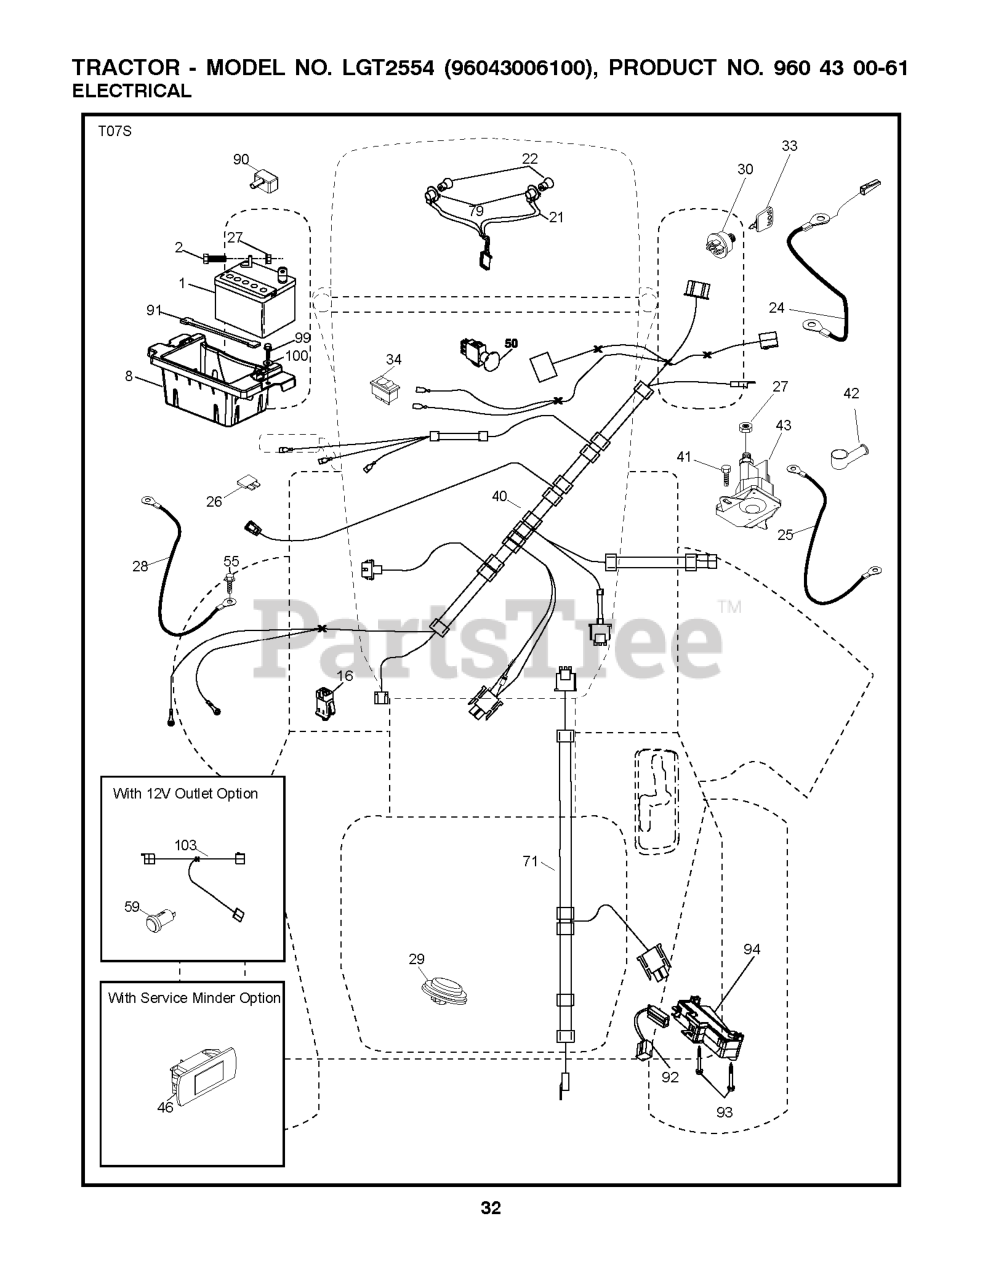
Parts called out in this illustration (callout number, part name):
1	Battery 12 Volt 25 Amp
2	BOLT.HEX.1/4.X.3/4.DICHROMATE
8	BOX.BATTERY.MOUNT.FRONT.LT
16	SWITCH INTERLOOK PUSH-IN
21	HARNESS ASSY LIGHT
24	CABLE.BATT.POS.WIRE.TG.DA SOL
25	CABLE.STARTER.6G.BL/RED.17.5
26	FUSE 20AMP
27	NUT
28	CABLE GROUND 6 GA 21" 90T BLK
29	SWITCH.SEAT.DELTA.OPC.
30	SWITCH.IGN.DELTA.W.LGH.ROS
33	KEY.CHAIN.BLISTER.PACK.GEN.INT
40	HARNESS.IGN.DASH.HUQ/P
41	SCREW
42	TERMINAL COVER
43	SOLENOID.W/BRASS.PLUNGER
46	RP.GUAGE.SRVCMNDR.HRMTR.
50	RP.PTO.SWITCH.8 TERMINAL.BLACK
55	SCREW 5/16"
59	OUTLET.12-VOLT
71	HARNESS-CHASSIS SUB
79	BULB HOLDER ASM.
90	COVER.TERMINAL.BATTERY
91	STRAP.BATTERY.MOUNT.FRONT(2 2)
92	HARNESS.PIGTAIL.CONSLE
93	SCREW.PLASTITE
94	MODULE.REVERSE.ROS
99	SCREW HEXWSHR 1/4-20X3/4
103	HARNESS PIGTAIL 12V OUTLET
